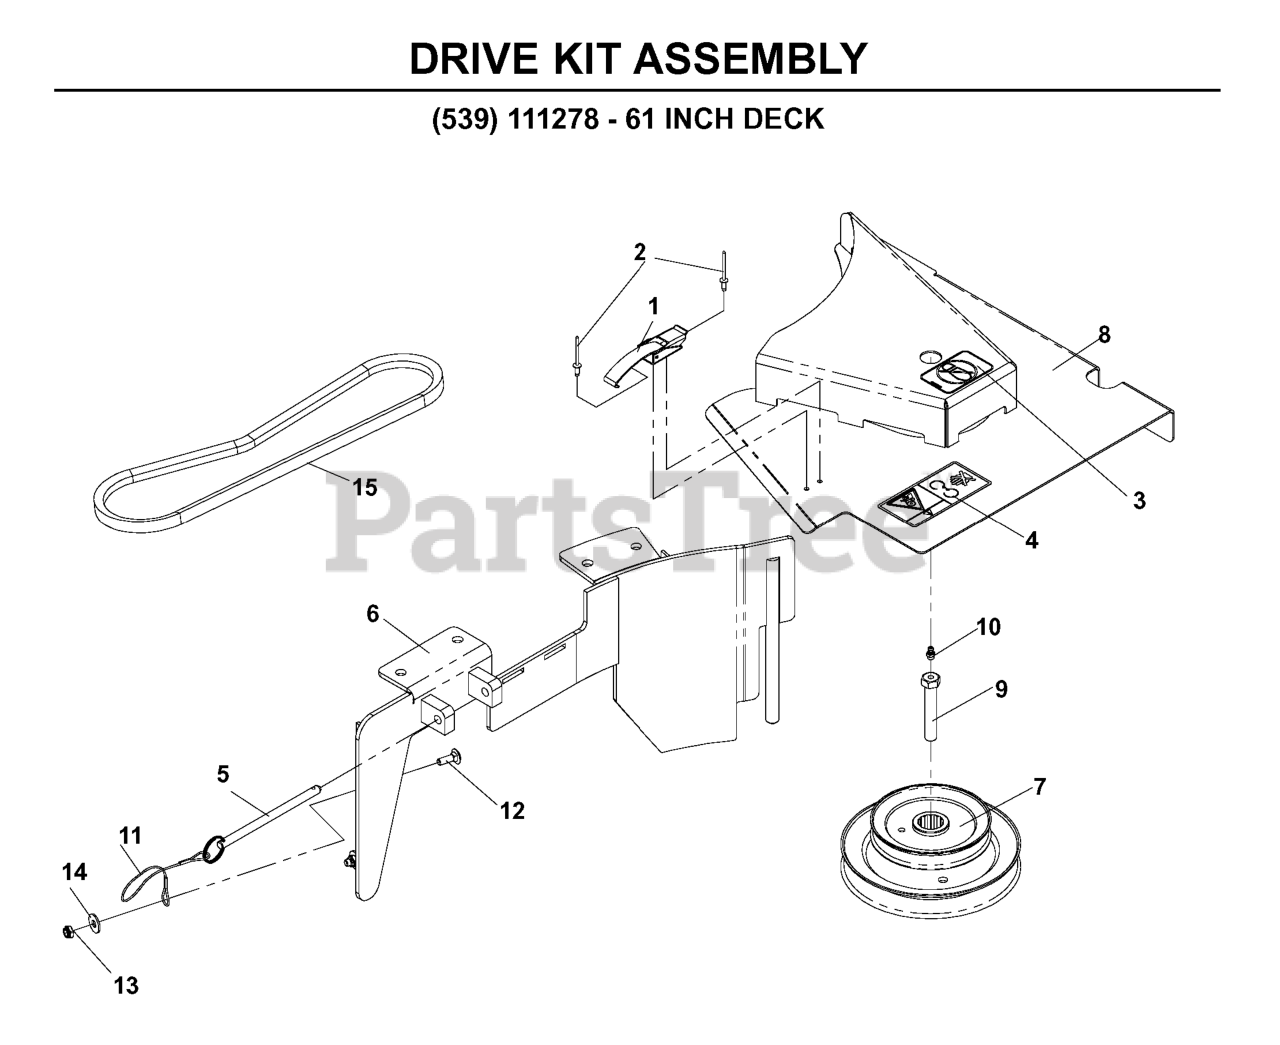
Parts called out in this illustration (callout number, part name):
1	DRAW LATCH
2	RIVET, BLIND, 5/32 DIA
3	DECAL, NO STEP
4	DECAL, BELT DRIVE
6	BLOWER DECK PLATE WLDMNT, 61"
7	61 LNG DBL HEX STK PULLEY
8	BELT SHIELD ASSY 61"
9	DRILLED BOLT 7/16-20 X 2 1/2"
10	ZERK
12	RHSNB 1/4C X 3/4
13	WASHER 1/4 FLAT
14	JAM NUT 1/4C (2 2 PW01)
